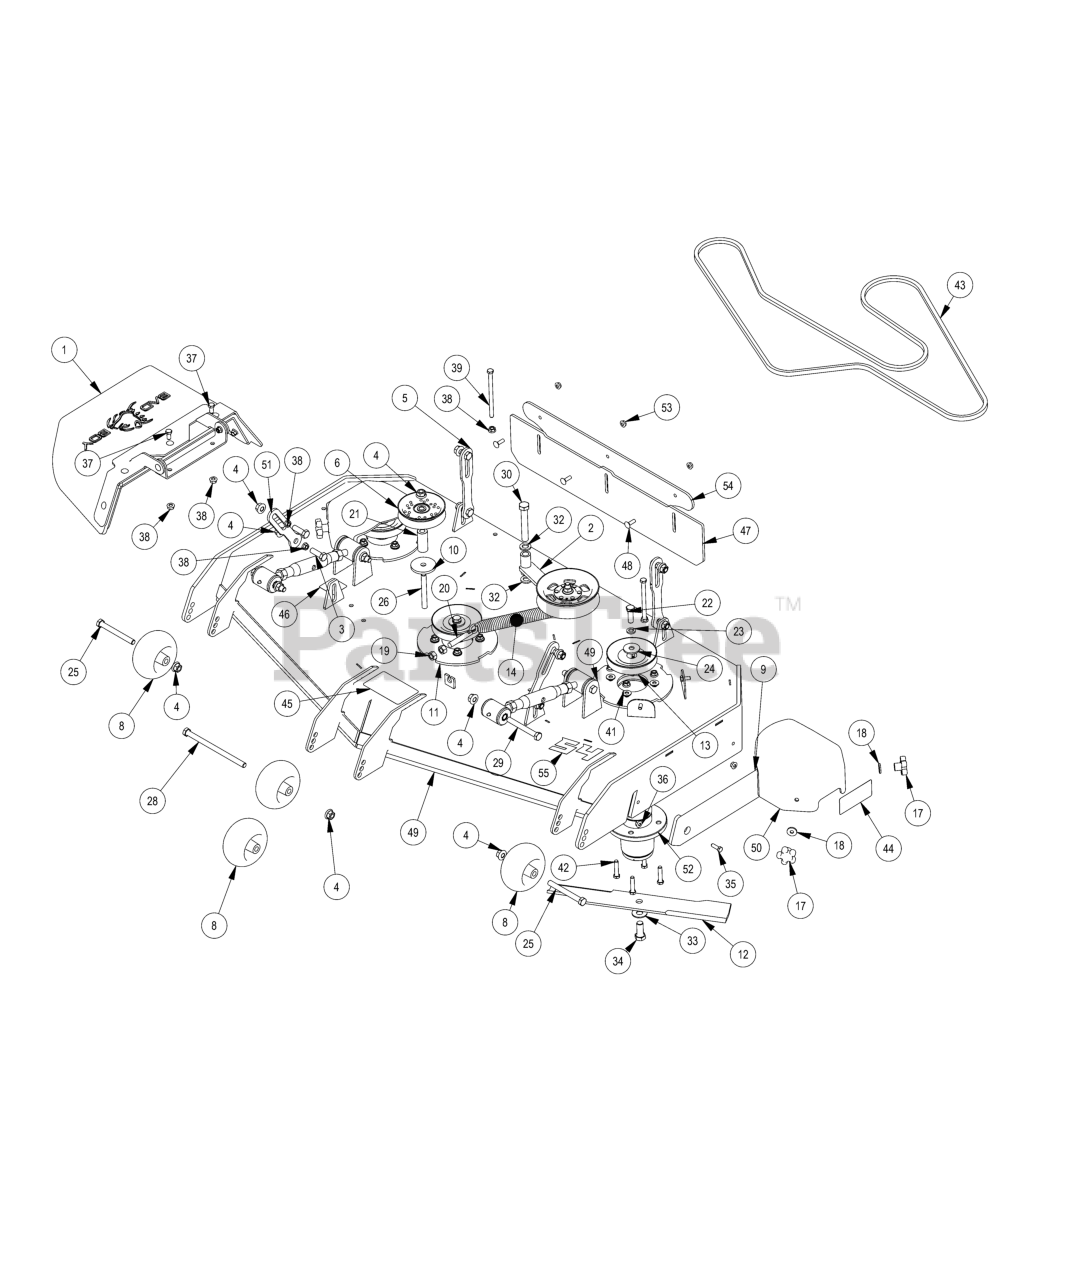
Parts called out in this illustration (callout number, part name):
1	2019 Outlaw Gen2 Chute Assembly
2	2019 Revolt Deck Idler Assembly
3	1/2-13 X 1-1/2 HEX CAP SCREW (GR.5) ZINC
4	1/2-13 NYLON INSERT FLANGE LOCKNUT ZINC
5	2023 Stand-On Rear Deck HangerV2
6	4 3/4 Idler Pulley - ABFI-76
7	Turnbuckle
8	2019 Deck Wheel
9	REVISED TRIM BUMPER_20180226
10	MZ Deck Idler Spacer
11	Deck Spindle Support Plate
12	54" Fusion Blade for ZT/Mav/Outlaw/Revolt
13	5" Spindle Deck Pulley
14	2019 Outlaw Gen2 Deck Spring
15	5/16-24 X 1/4 SOCKET SET SCREW (CUP PT) PLAIN
16	1/4 X 1 SQ MACHINERY KEY 1018 STL PLN
17	5/16" Knob
18	.360 ID X .983 OD X .120 THICK FLAT WASHER NYLON BLACK
19	1/2-13 HEX NUT ZINC
20	All Thread
21	2019 Revolt Stationary Idle Spacer
22	1/2-20 X 1-1/2 HEX CAP SCREW (GR.5) ZINC
23	1/2 SPLIT LOCKWASHER (GR.8) ZINC/YELLOW
24	1/2 BELLEVILLE WASHER (1-5/8 OD X .140 THK) ZINC
25	1/2-13 X 4-1/2 HEX CAP SCREW (GR.5) ZINC
26	1/2-13 X 4-1/4 HEX CAP SCREW (GR.5) ZINC
27	1.02 ID X 1.38 OD X .250 THK SPACER ZINC
28	1/2-13 X 8 HEX CAP SCREW GR 5 ZINC
29	1/2-13 X 4 HEX CAP SCREW (GR.8) ZINC YELLOW
30	5/8-11 X 4 HEX CAP SCREW (GR.8) ZINC YELLOW
31	5/8-11 NYLON INSERT JAM LOCKNUT ZINC
32	.635 ID X 1.120 OD X .140 THICK FLAT WASHER NYLON
33	5/8 USS FLAT WASHER (1-3/4" OD) GR.8 ZINC YELLOW
34	5/8-18 X 1-1/2 HEX CAP SCREW (GR.8) ZINC YELLOW
35	5/16-18 X 1 HEX CAP SCREW (GR.5) ZINC
36	5/16-18 NYLON INSERT FLANGE LOCKNUT ZINC
37	3/8-16 X 3/4 HEX CAP SCREW (GR.5) ZINC
38	3/8-16 HEX SERRATED FLANGE NUT HARD/ZINC
39	3/8-16 X 5-1/2 HEX CAP SCREW (GR.5) ZINC
40	3/8-16 NYLON INSERT FLANGE LOCKNUT (GR.F) ZINC
41	5/16 USS FLAT WASHER (7/8 OD) ZINC
42	3/8-16 X 1-3/4 HEX C/S (GR.5) ZC
43	42 inch Deck Belt- B120
44	Danger Decal-Spindle/Discharge
45	2019 Revolt Deck Belt Route Decal
46	Deck Impact Patent Decal 9591803
47	2023 MZ Stripping Kit Rubber
48	5/16-18 X 1 CARRIAGE BOLT (GR.8) ZINC
49	2023 54'' DECK
50	2023 Revolt pulley cover
51	Deck Hangar
52	OUTLAW SPINDLE ASSEMBLY
53	5/16-18 HEX SERRATED FLANGE NUT HARD/ZINC
54	Striping Kit Plate
55	54" Deck Decal
